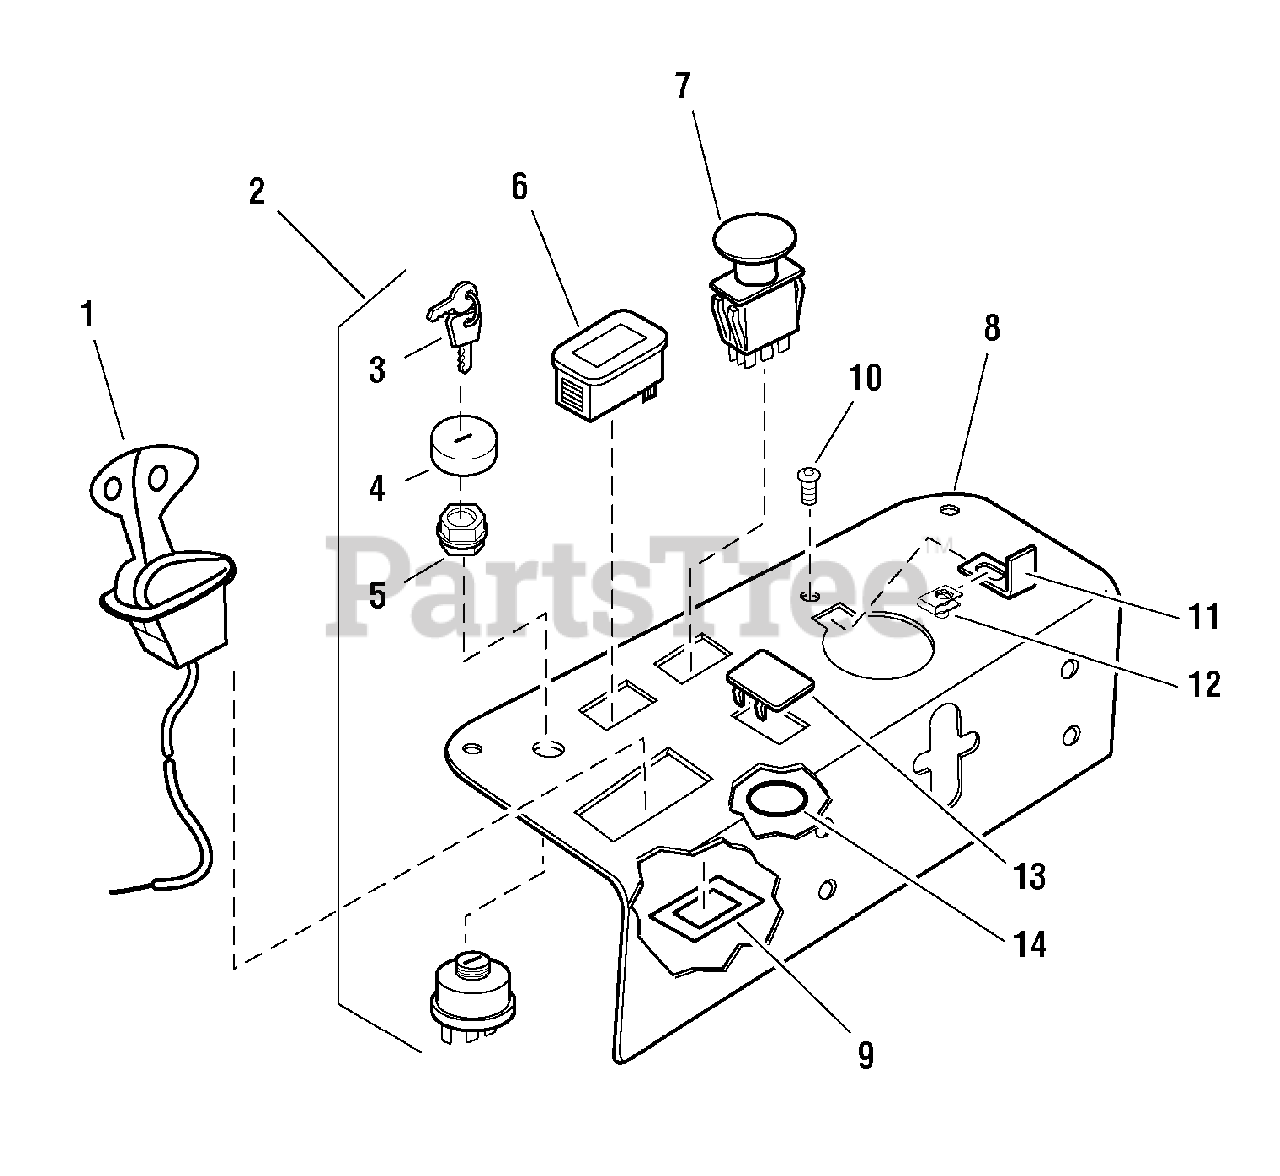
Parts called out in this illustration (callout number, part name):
1	LEVER, Dual Choke/Throttle
2	SWITCH, Ignition, (Includes Ref 3-5)
3	KEY, Ignition Molded (Set of 2)
5	NUT, Plastic
6	HOUR METER, Digital (Includes Retaining Ring)
7	SWITCH, PTO
8	CONTROL PANEL
9	RING, Switch Retainer
10	CAPSCREW, Button Allen Head, 1/4-20 x 3/4
11	BRACKET, Lock
12	BODY CLIP, 1/4-20
